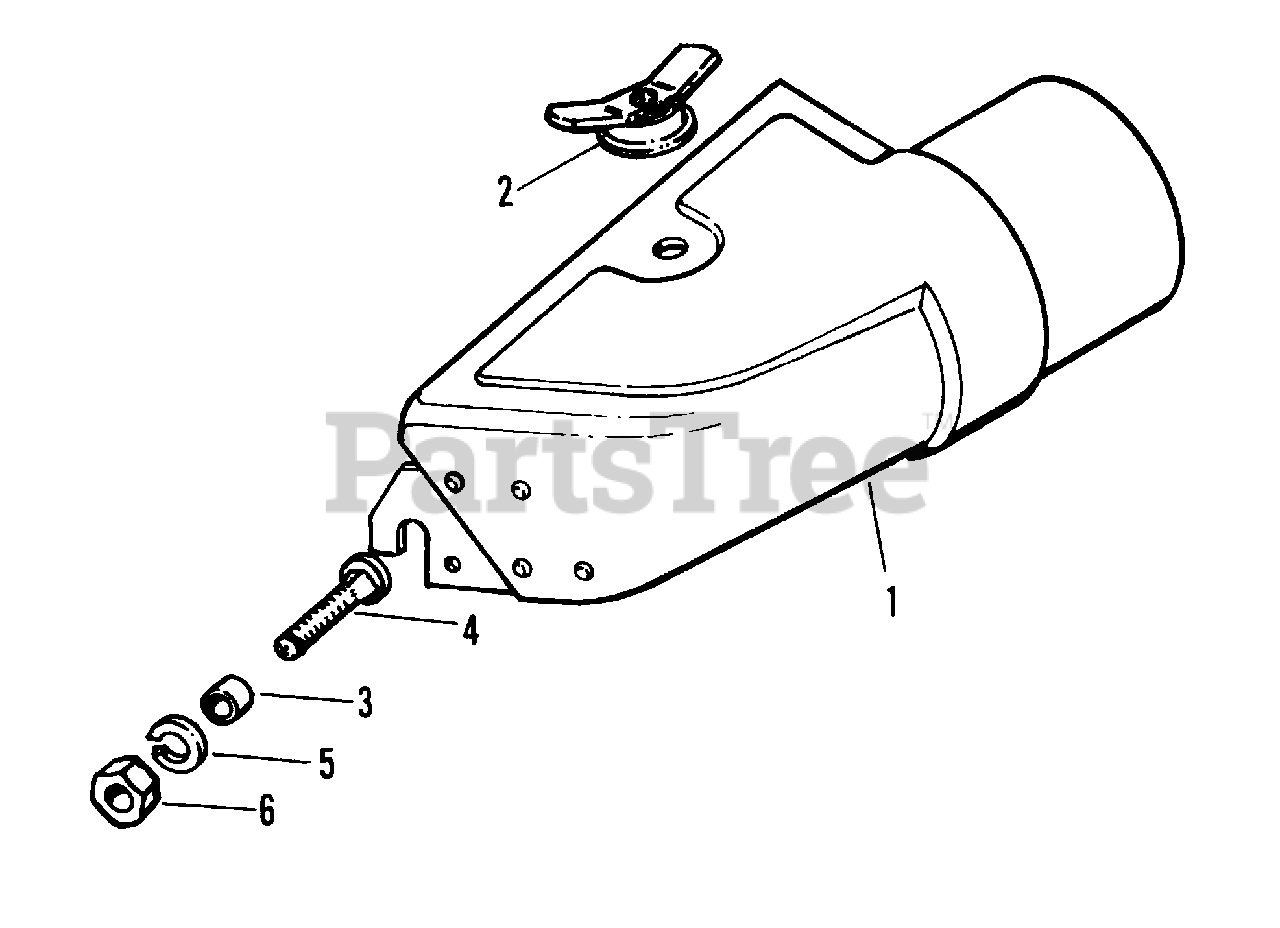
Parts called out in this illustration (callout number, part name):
1	36" ADAPTER ASSEMBLY
2	NUT ASSEMBLY
4	BOLT, Rd. Hd., Sq. Nk., 5/16-18 x 1
5	LOCKWASHER, 5/16
6	NUT. Full hex, 5/16-18
